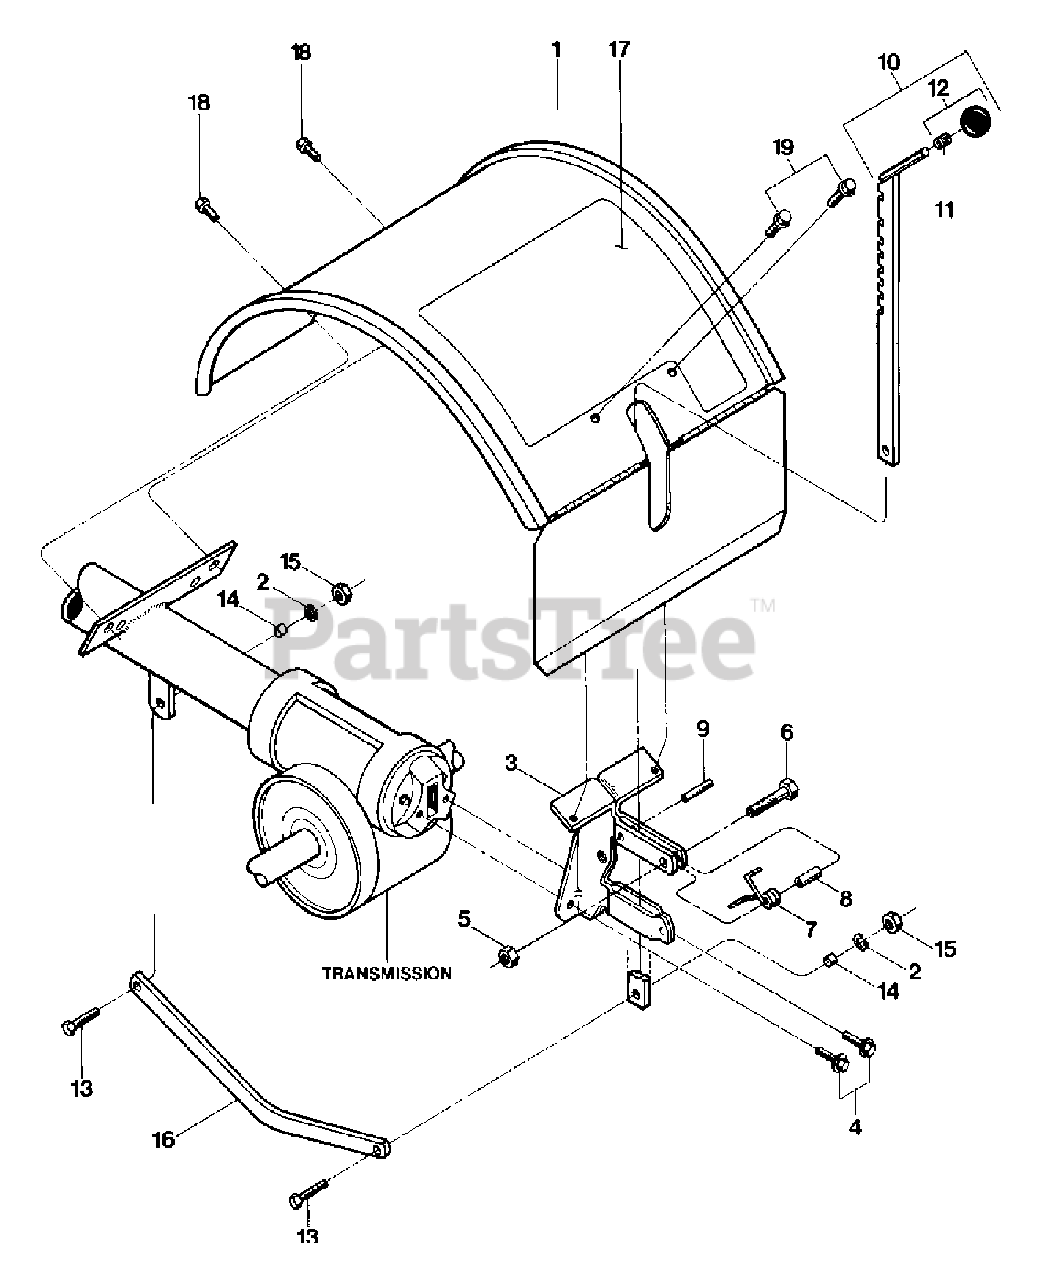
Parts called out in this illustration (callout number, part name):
1	Tine Hood
2	Lockwasher, 3/8
3	Bracket-hood & depth regulator
4	Hex Flange Screw, 5/16-18 x 5/8
5	Hex Locknut, 1/4-20
6	Hex Hd. Screw, 1/4-20 x 1
7	Spring
9	Roll Pin (spiral), 1/4 x 1
10	Depth Adjustment Bar Assembly
11	Retaining Ring (tolerance ring)
12	Knob, Depth Regulator
13	Hex Hd. Screw, 3/8-16 x 1-1/4
14	Bushing, Drag Bar
15	Hex Nut, 3/8-16
16	Drag Bar
17	Decal, operating instructions
18	Hex Hd. Screw, self-tapping, 5/16-18 x 1/2
19	Hex Flange Screw, self-tapping, 1/4-20 x 1/2
